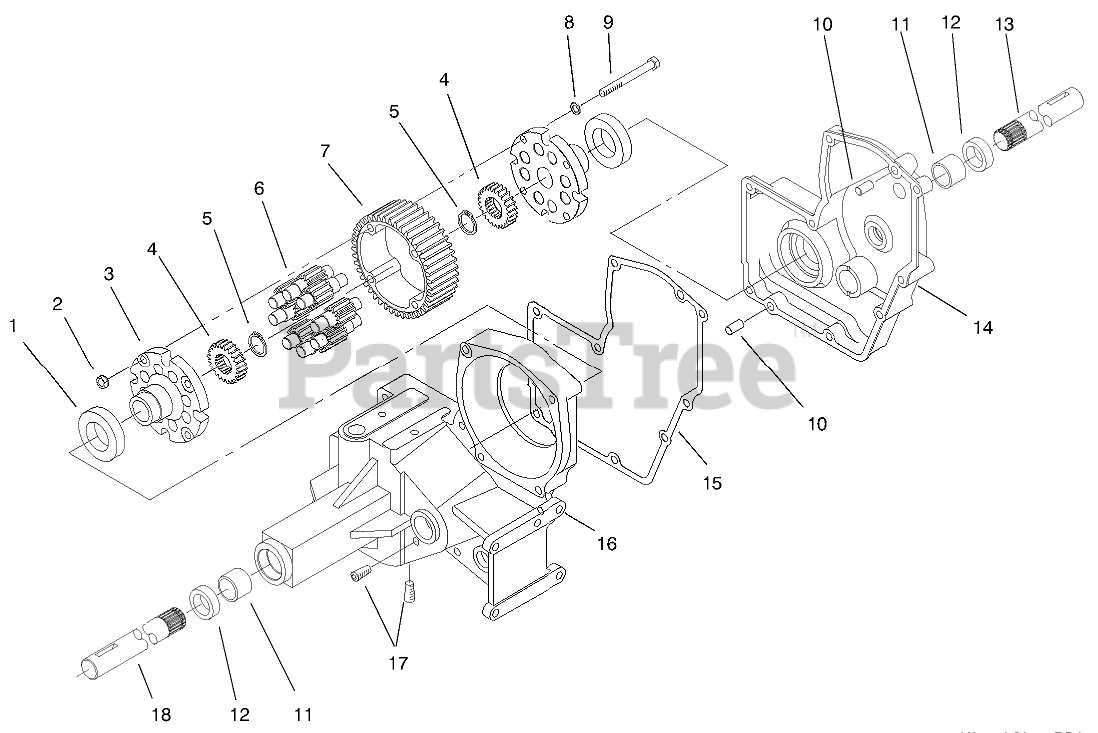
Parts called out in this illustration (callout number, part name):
1	BEARING-BALL
3	END CAP-DIFFERENTIAL
4	GEAR-AXLE DIFFERENTIAL
5	RING-SNAP
6	GEAR-PINION, 11T
7	GEAR-DIFFERENTIAL RING, 43T
8	WASHER
9	BOLT-HEX
10	PIN-LOCATING
11	BEARING
12	SEAL-OIL
13	AXLE-REAR LH
14	Case-Transaxle
15	GASKET-TRANSMISSION
16	Case-Transaxle
16	CASE-TRANSMISSION RH
16:1	Case-Transaxle
16:2	DECAL - DANGER
18	AXLE-REAR RH
